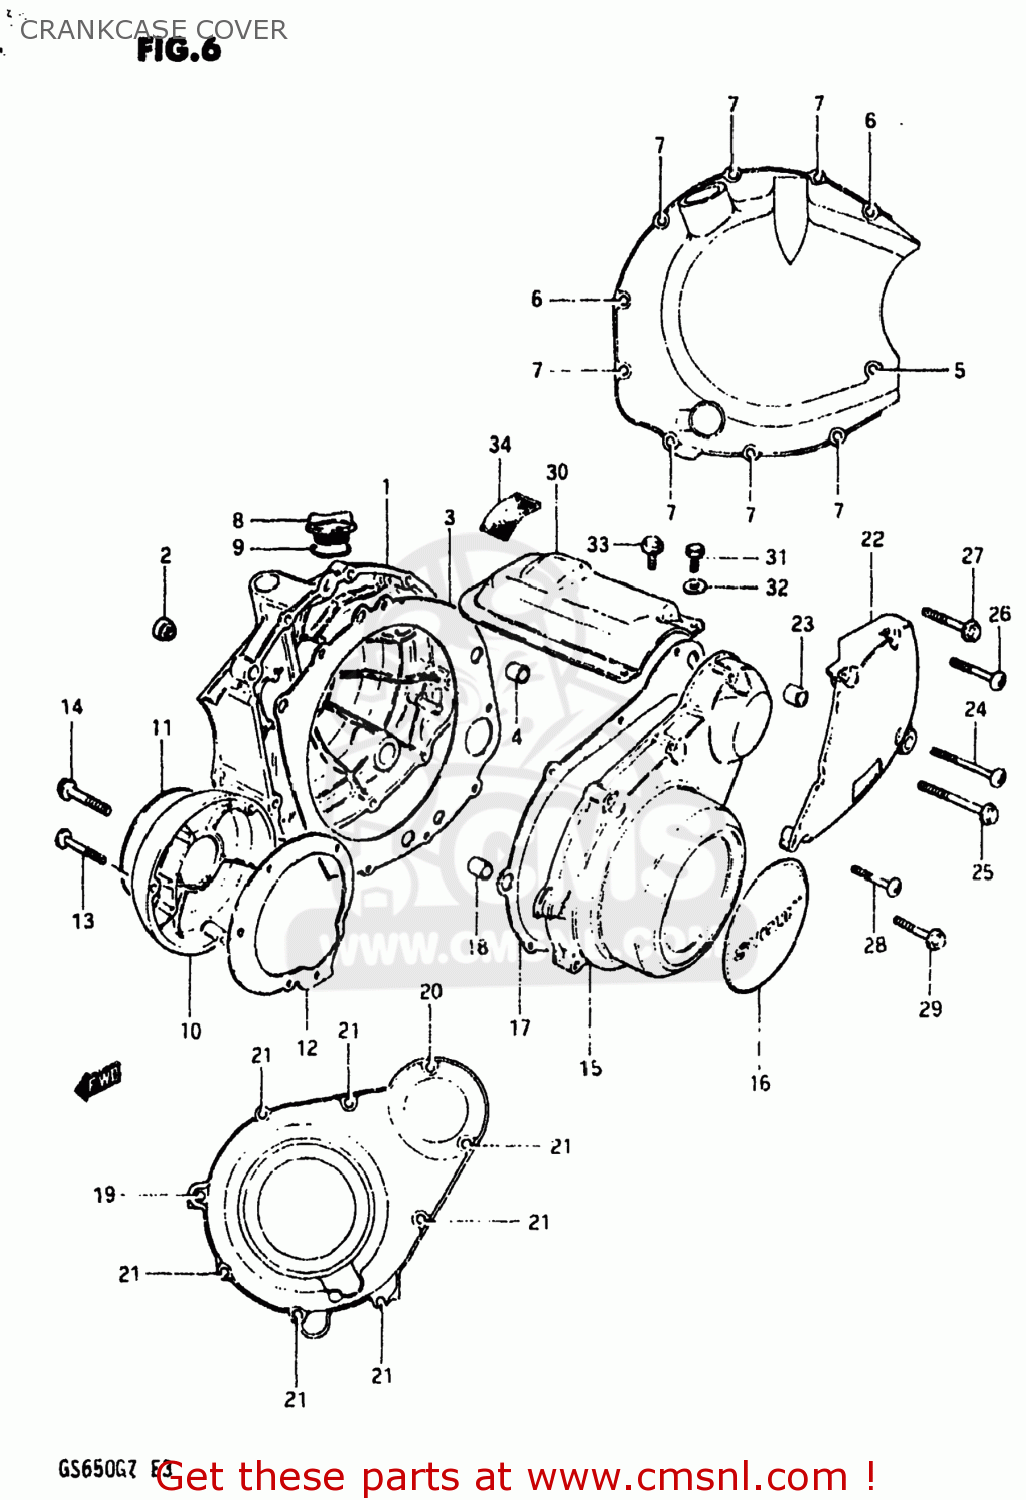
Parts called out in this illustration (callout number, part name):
1	COVER,CLUTCH
2	LENS,OIL LEVEL CHECK
3	GASKET,CLUTCH COVER (MCA)
4	PIN
5	SCREW 6X65
6	SCREW
7	SCREW 6X30
8	PLUG
9	O-RING
10	COVER,CONTACT BREAKER
11	EMBLEM,CONTACT BREAKER COVER
12	GASKET,CONTACT BREAKER COVER (NAS)
13	SCREW
14	BOLT (5*30)
15	COVER
16	EMBLEM,MAGNETO COVER
17	GASKET,MAGNETO COVER (MCA)
18	PIN
19	BOLT
20	SCREW
21	SCREW 6X30
22	COVER,SPROCKET
23	PIN
24	SCREW
25	BOLT (6X40)
26	SCREW 6X30
27	BOLT (6X30)
28	SCREW
29	BOLT
30	COVER
31	BOLT 5X16
32	WASHER
33	BOLT
34	DAMPER,STARTER MOTOR CLUTCH
